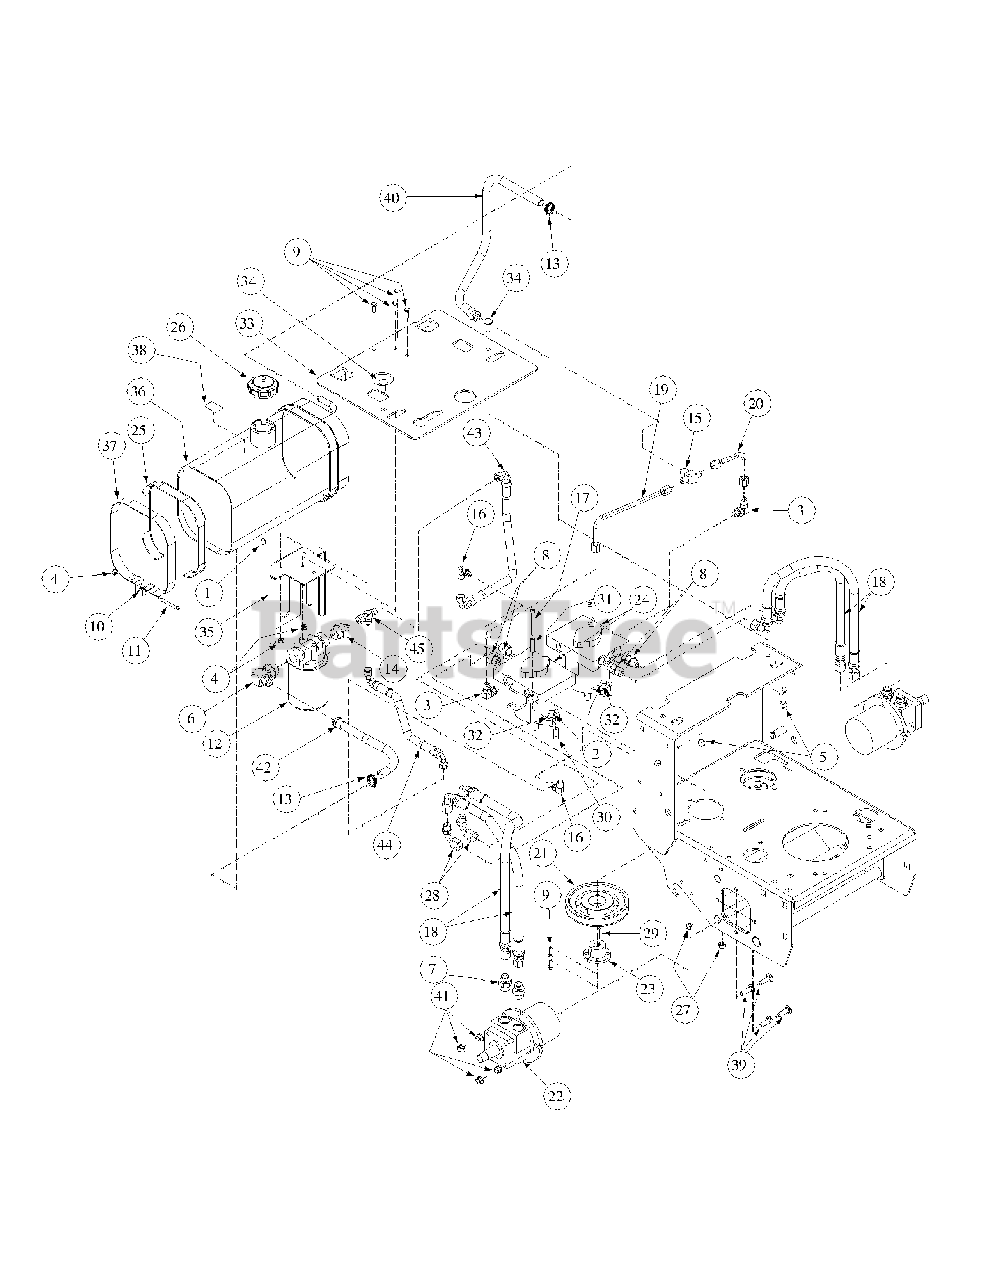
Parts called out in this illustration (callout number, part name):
1	Plug, 1/4"
2	Cap Screw, Standard, 3/8-16 x 1-1/4
3	Fitting, Aeroquip
4	Lock Nut, 1/4-20
5	Lock Nut, 3/8-16
6	Elbow 90° 1/2 x 3/4
7	Fitting, Aeroquip
8	Fitting, Aeroquip
9	Cap Screw, 1/4-20 x 3/4
10	Hex Nut, 1/4-20
11	Machine Screw, 1/4-20 x 2, Zinc
12	Filter Head 3/4
12	Oil Filter
13	Clamp Wormgear, 5/16-7/8
14	Straight Connector 1/2 x 3/4
15	Fitting Aeroquip
16	Fitting, Aeroquip
17	Cap Screw, Socket Head, 1/4-20 x 2-1/2 Zinc
18	Hydro Hose Assembly, Reverse Pressure
19	Hydraulic Line, Pump Return Long
20	Hydraulic Line, Pump Return Short
21	Deck Pulley
22	Hydraulic Motor, Wheel
23	Bushing, 15mm Bore, Split, Type "D"
24	Pump Hydro BDP10L117
25	Pad, Oil Tank
26	Cap, Hydraulic Oil Tank
27	Lock Nut, 3/8-16
28	Fitting Aeorquip
29	Pump Key
30	Nut, Pump Release
31	Spacer, Pump Release
32	Washer, Idler
33	Fuel Tank, Mounting Plate
34	Carriage Bolt, 3/8-16 x 2
35	Filter Guard
36	Oil Tank w/Neck
37	Oil Tank Strap
38	Oil Label, 20W-50
39	Carriage Bolt, 3/8-16 x 1.25
40	Hose Assembly
40	Hose Hydraulic 22"
41	Hex Nut, Flange Lock, 3/8-16
42	Hose, Filter to Tank
43	Hose, Filter to Left Pump
44	Hose, Filter to Right Pump
45	Fitting, Aeroquips
